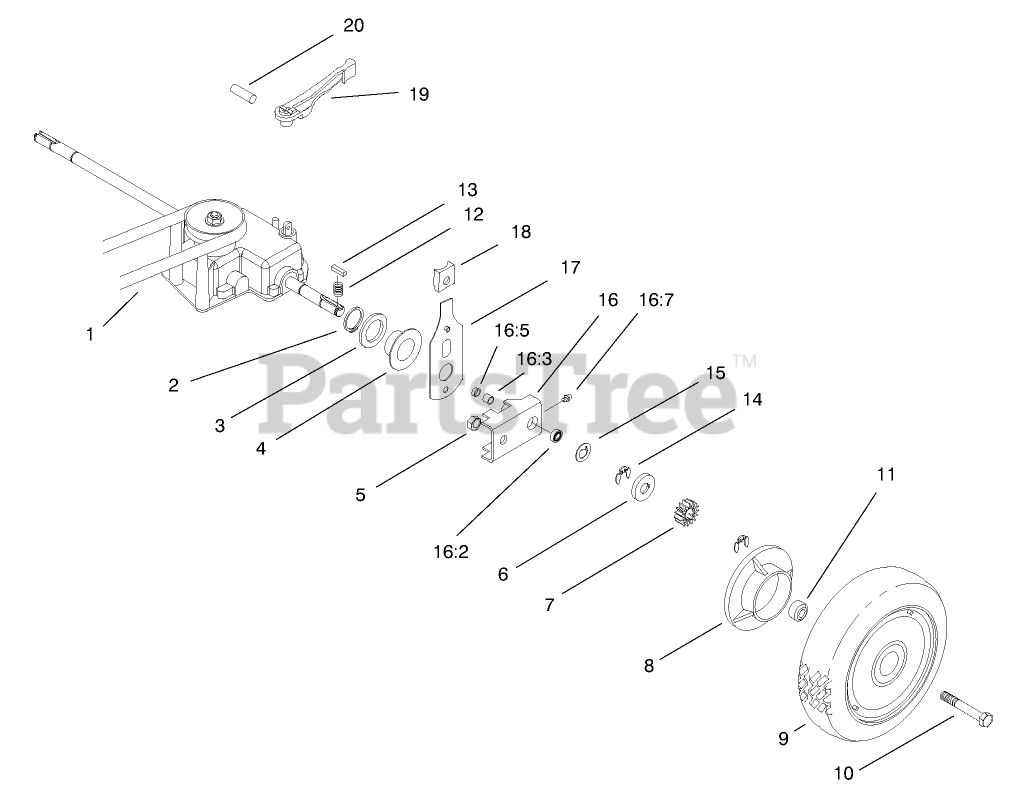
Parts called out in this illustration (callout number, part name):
1	V-BELT
2	RING-RETAINING
3	WASHER
4	CAP-END
5	NUT-LOCK, CONE
6	WASHER-THRUST, OUTER
7	GEAR-PINION
8	COVER-WHEEL
10	SCREW-HH
11	SPACER-COVER, WHEEL
12	SPRING-COMPRESSION
14	RING-RETAINING
15	WASHER-THRUST, OUTER
16	PIVOT ARM ASM
16:2	BEARING-WHEEL
16:5	SEAL-OIL
17	REAR SPRING ARM ASM
18	KNOB-ARM
19	LEVER-SHIFT
20	PIN-SPRING
